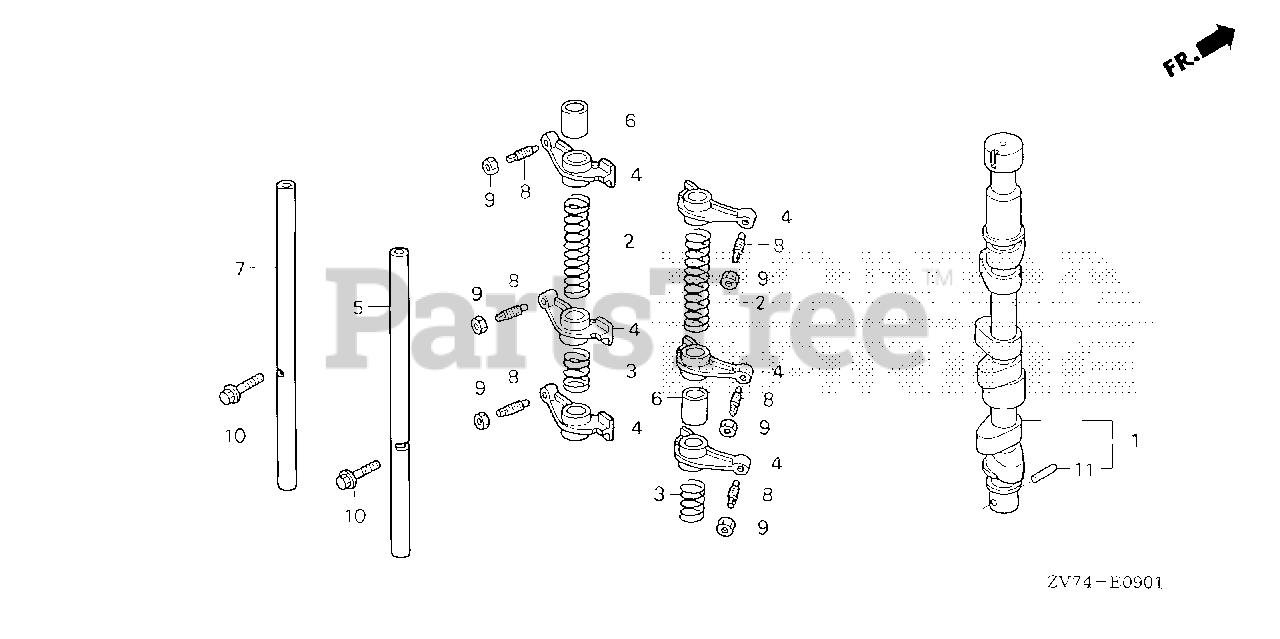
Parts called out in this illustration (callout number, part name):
2	SPRING, ROCKER ARM A
3	SPRING, ROCKER ARM B
4	ARM, VALVE ROCKER
5	SHAFT, IN. ROCKER ARM
6	COLLAR, ROCKER
7	SHAFT, EX. ROCKER ARM
8	SCREW, TAPPET ADJUSTING
9	NUT, TAPPET ADJUSTING
10	BOLT, FLANGE (6X28)
11	ROLLER (3X16.8)
